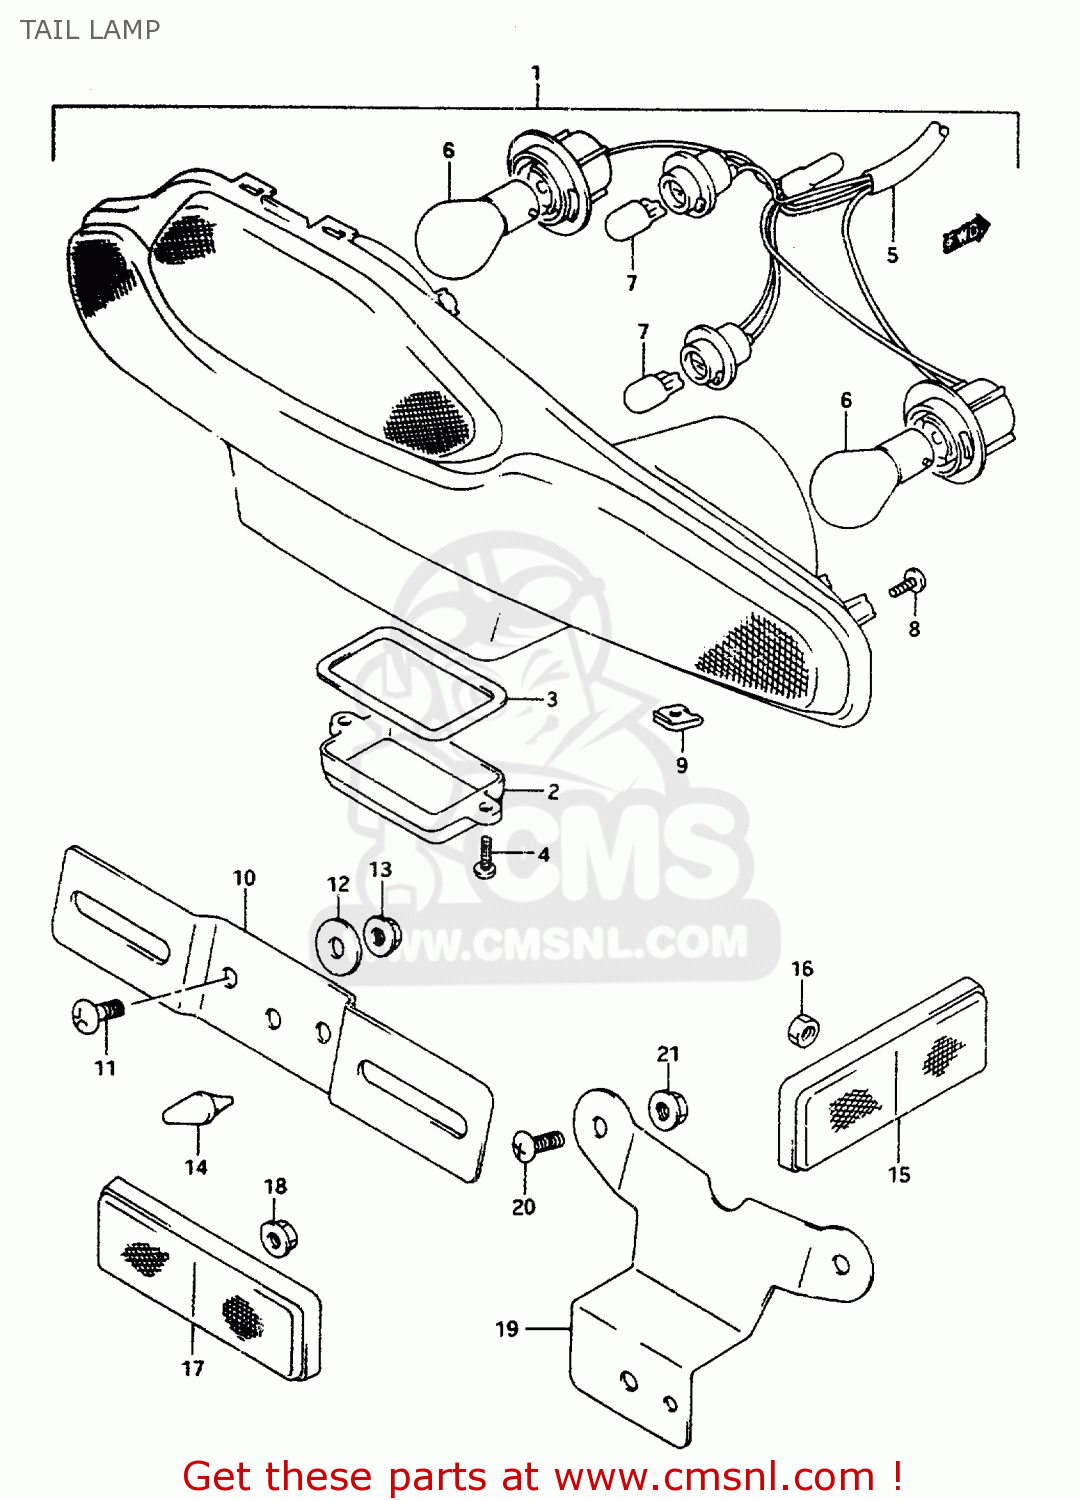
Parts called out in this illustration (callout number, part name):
1	LAMP ASSY,RR COMBINATION
2	LENS,LICENSE LAMP
3	GASKET (NAS)
4	SCREW
5	SOCKET & CORD
6	BULB(12V21W)
7	BULB(12V5W)
8	SCREW
9	NUT
10	PLATE,RR LICENSE
11	SCREW 6X12
12	WASHER,COVER,FRONT
13	NUT
14	CUSHION
15	REFLEX REFLECTOR,FR SIDE
16	NUT
17	REFLECTOR ASSY,RR
18	NUT
19	BRACKET,RR REFLECTOR
20	SCREW 6X12
21	NUT
